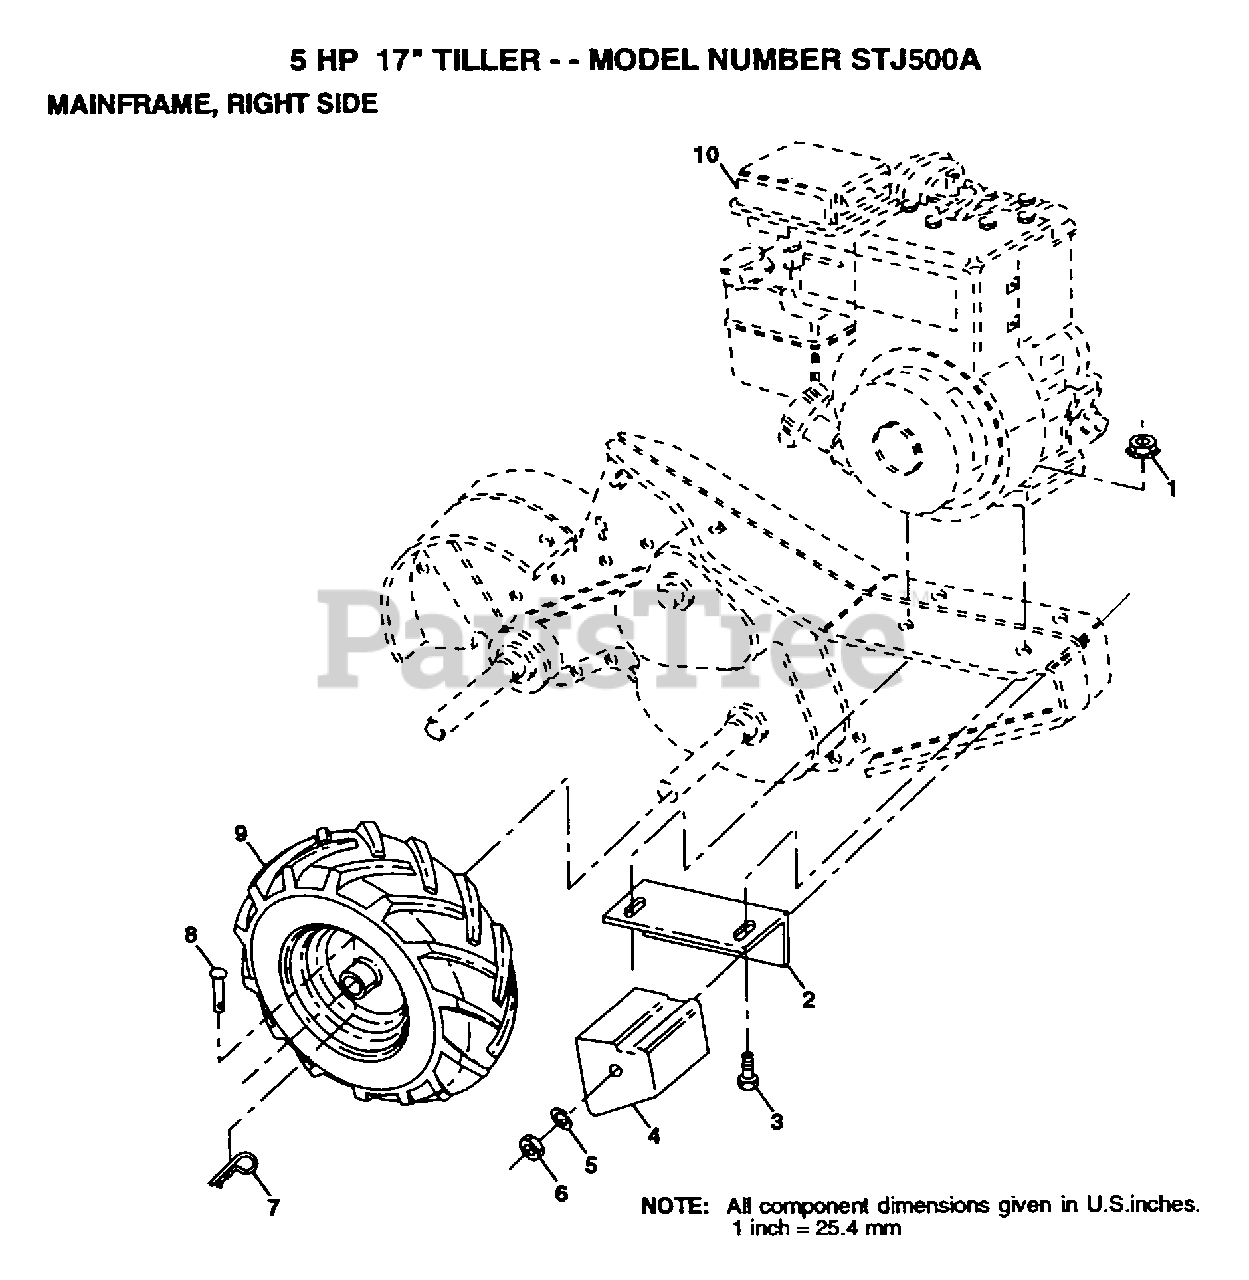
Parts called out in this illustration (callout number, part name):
2	BRACKET RH CRT
3	BOLT.HEX.5/16-1.5
4	COUNTERWEIGHT CRT
5	LOCKWASHER
6	NUT.HEX.3/8-16UNC
7	RETAINER M
8	RIVET.DRILL.1.75
9	TIRE.CHV.13X5.0-6
9	RIM
